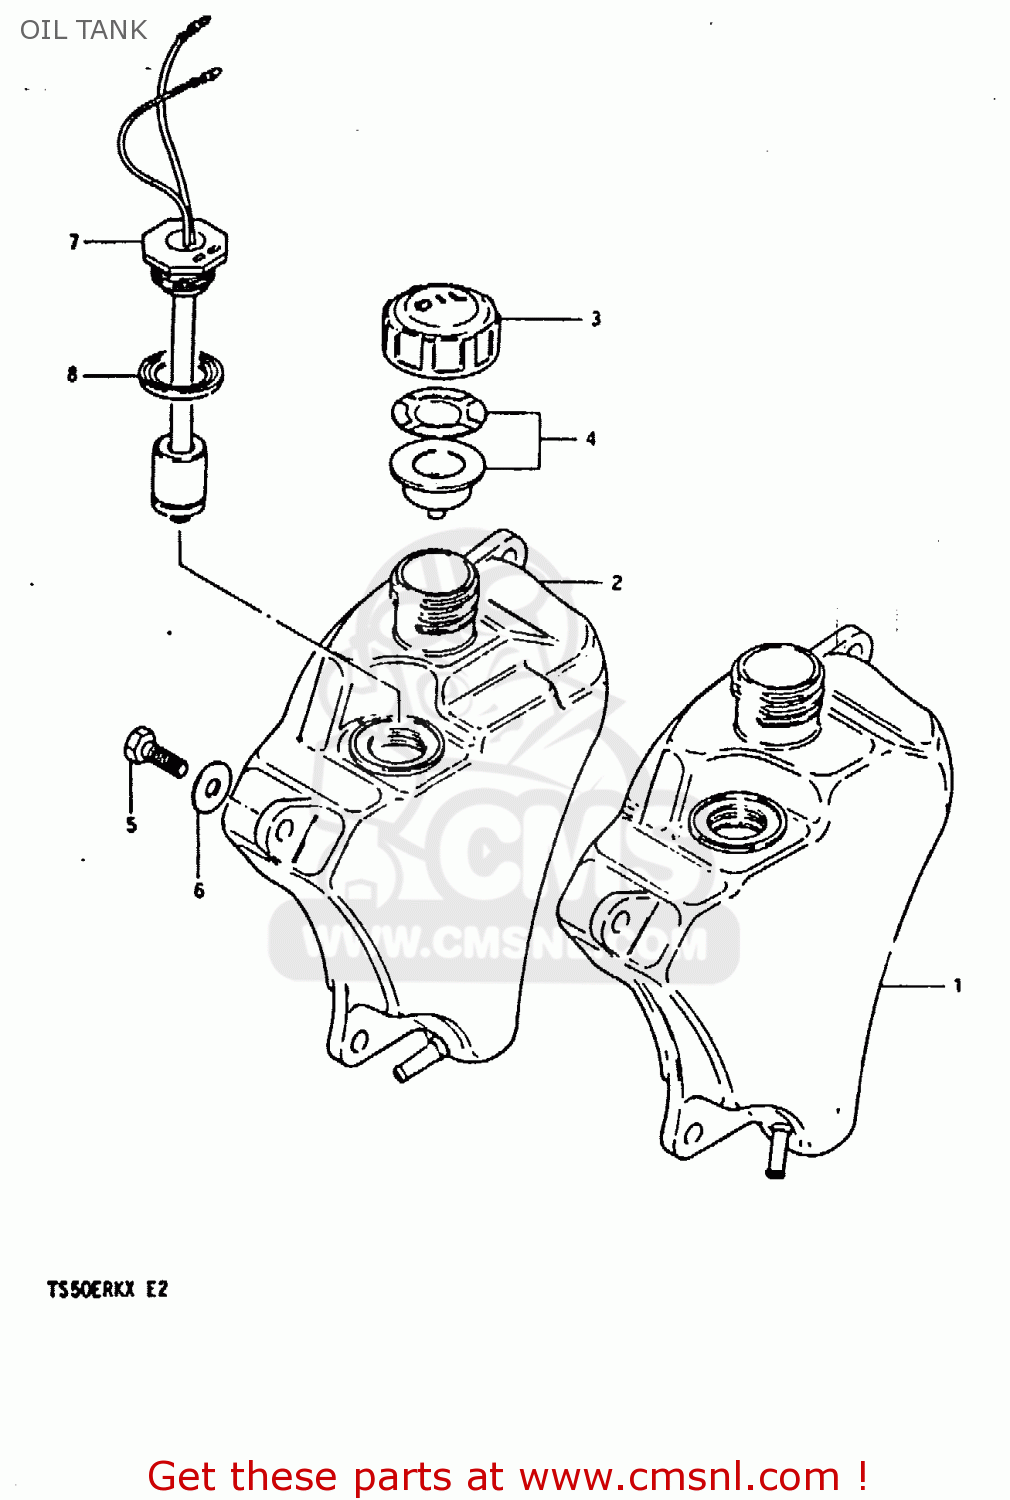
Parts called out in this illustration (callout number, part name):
1	TANK, OIL
2	TANK, OIL
3	CAP,OIL TANK
4	GASKET SET (NAS)
5	BOLT, UPPER
6	WASHER
7	SWITCH, OIL LEVEL
8	GASKET (NAS)
